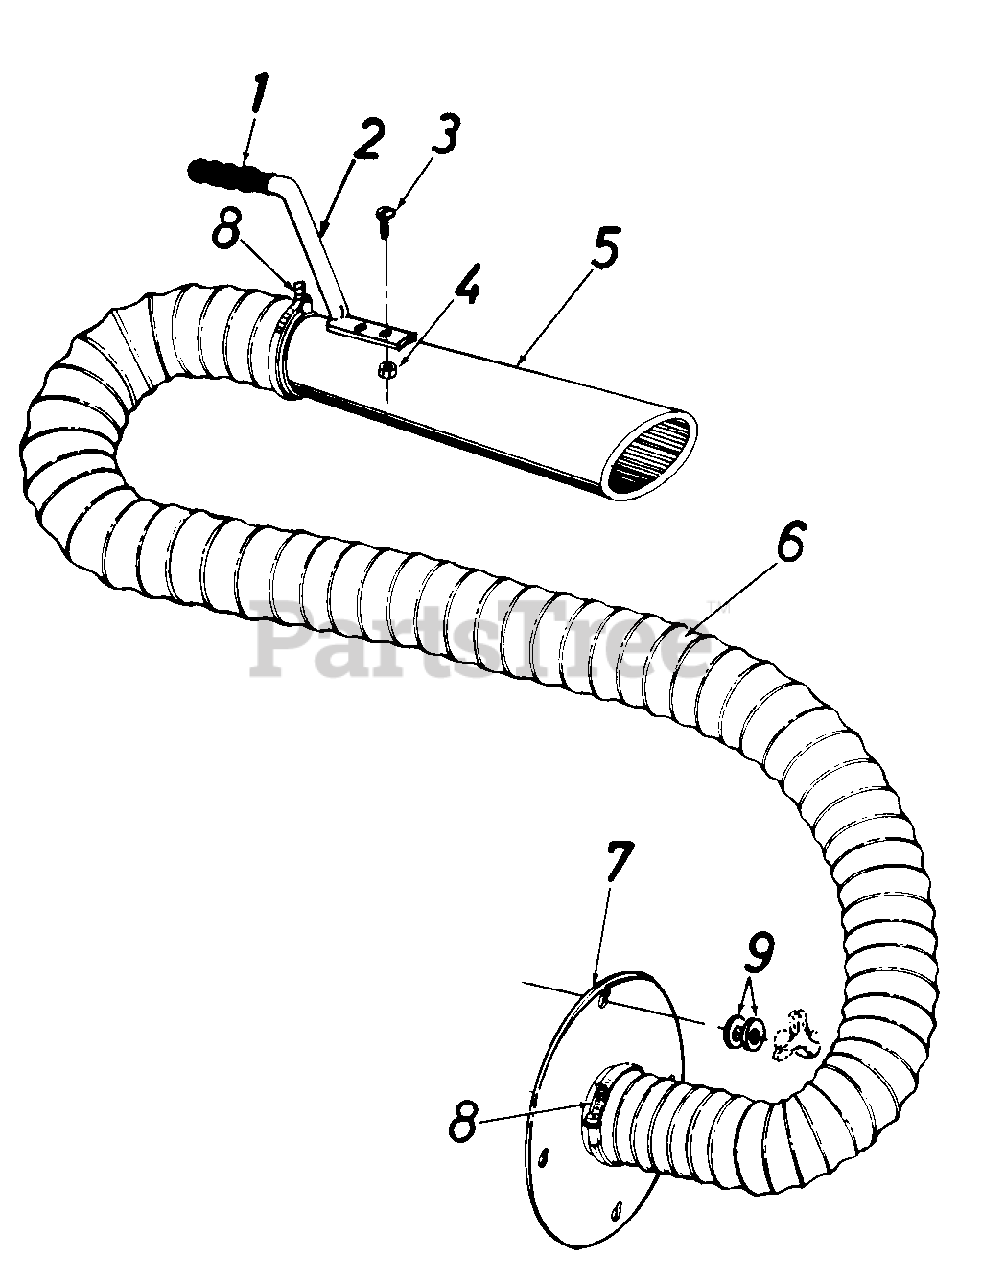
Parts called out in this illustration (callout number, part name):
1	GRIP-BLACK
2	HANDLE-HOSE NOZ LONG
3	SCREW-TRUSS SEMS #10-24 X .50
5	NOZZLE-HOSE
6	HOSE-4IN DIA X 10FT
9	WASHER-FL-.312 X 1.125 X .125
